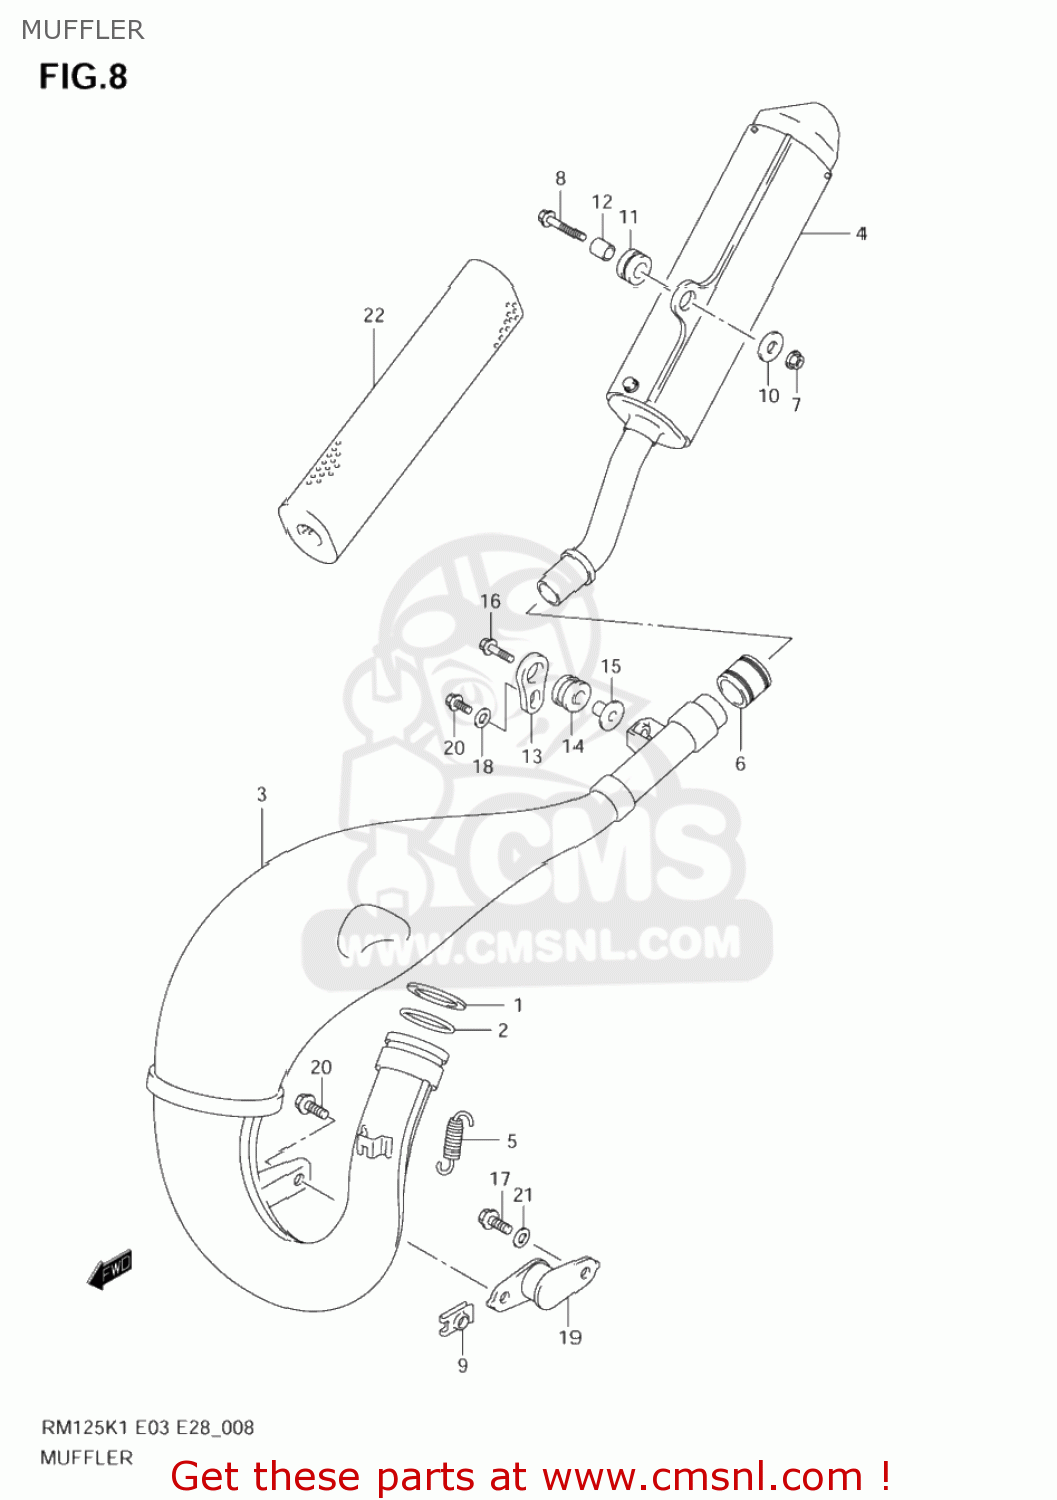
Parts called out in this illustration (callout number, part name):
1	WASHER,EXHAUST PIPE
2	O RING,EXHAUST PIPE
3	BODY,MUFFLER 1ST
4	BODY,MUFFLER 2ND
5	SPRING
6	CONNECTOR,MUFFLER
7	NUT
8	BOLT(6X30)
9	HOLDER,REAR BU
10	WASHER(6.5X24X1.2)
11	CUSHION
12	SPACER(6.5X11.5X12)
13	PLATE,MUFFLER MTG
14	CUSHION,MUFFLER
15	SPACER,MUF MTG
16	SCREW
17	BOLT
18	WASHER(6.5X18X1.6)
19	DAMPER,MUFFLER
20	BOLT
21	WASHER(6.5X18X1.6)
22	SILENCER,MUFFLER
